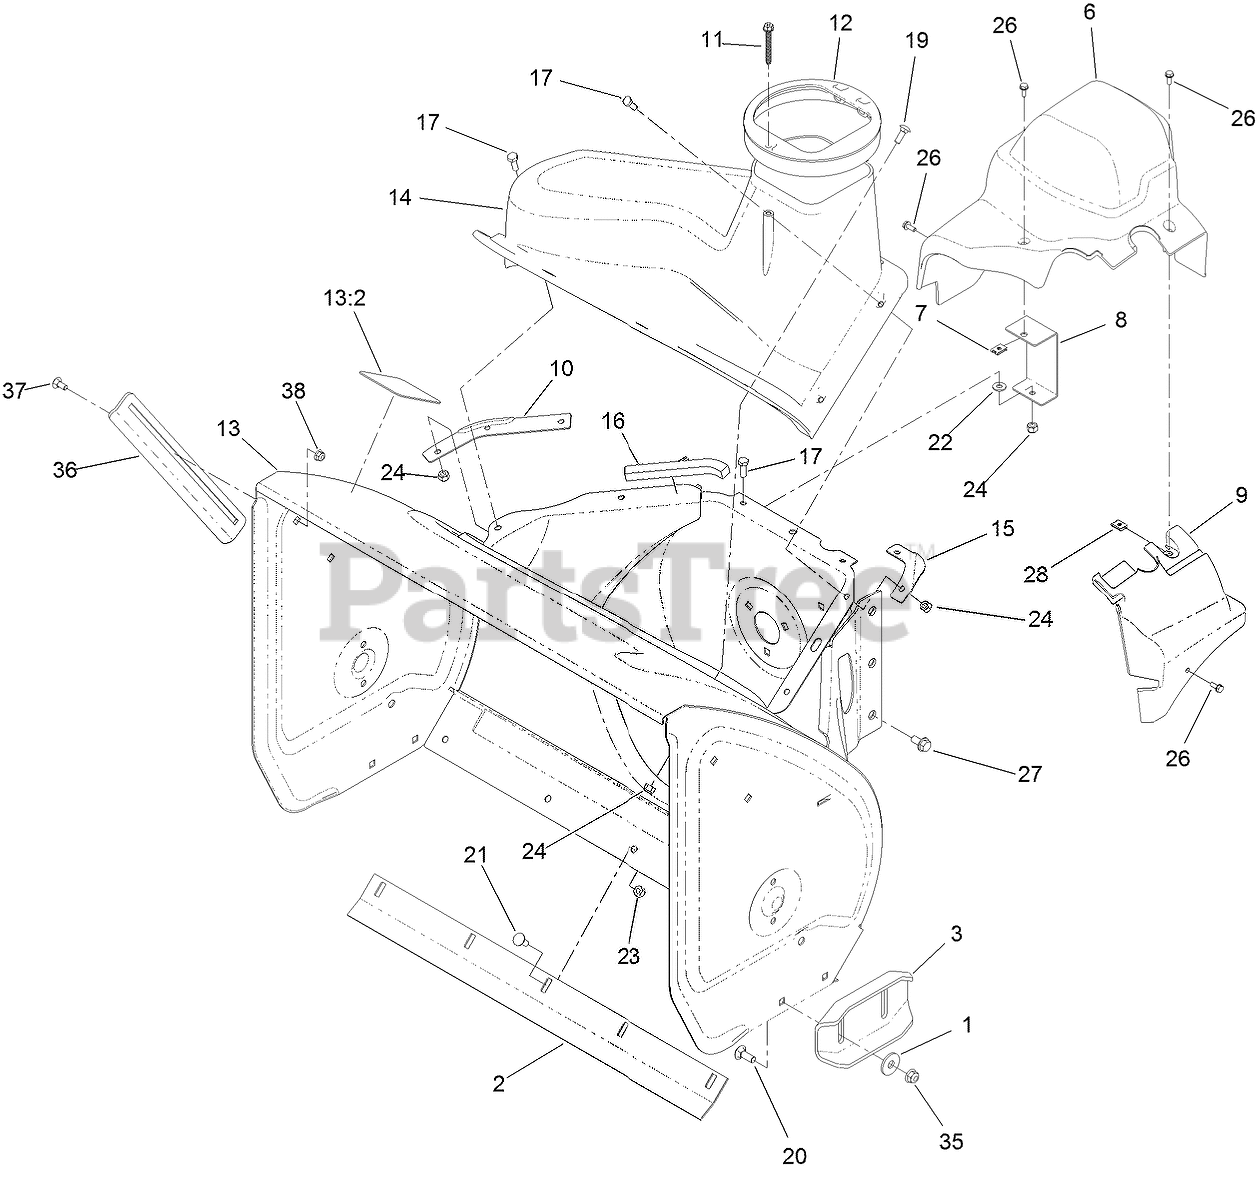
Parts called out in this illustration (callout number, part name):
1	WASHER
2	SCRAPER-FIXED
3	SKID-CAST
6	COVER-BELT
7	NUT-SPEED
8	BRACKET-COVER, CLIP NUT
9	COVER-EXTENSION, BELT
10	SEAL-FLANGE, COVER
11	SCREW-HWH, PLASTITE
12	GUIDE-CHUTE
13	HOUSING-AUGER, 28 INCH
13:2	DECAL-DANGER, AUGER
16	SEAL-HOUSING
17	SCREW-HH
19	BOLT-CARR
20	SCREW-CARR
21	SCREW-CARR
22	WASHER-FLAT
23	NUT-LOCK, NI
24	NUT-LOCK, NI
26	SCREW-HWH
27	SCREW-HWHTF
28	NUT-SPEED
35	NUT-HF, NI
36	BREAKER-DRIFT, SIDE
37	BOLT-CARR
38	NUT-HF, NI
